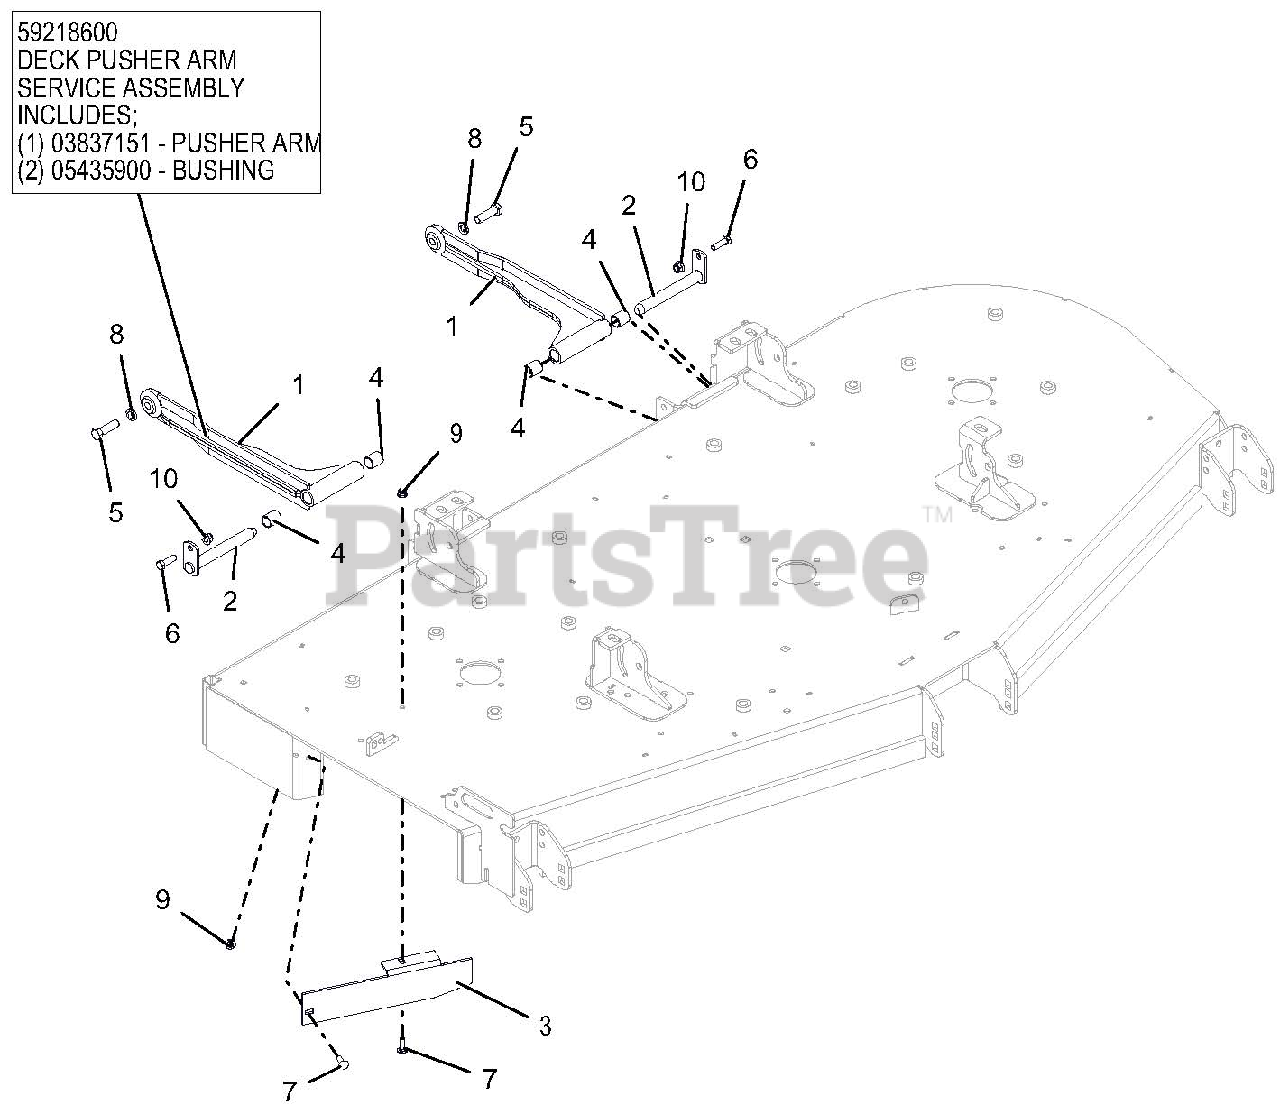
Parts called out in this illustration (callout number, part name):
1	DECK STABILIZER ARM - BLACK
1	DECK STABILIZER ARM W/BUSHINGS
1	BRG, .750 X .875 X 1.000
2	WELDMENT, MOWER MTG. PIN
3	72" DISCHARGE BAFFLE - RED
4	BRG, .750 X .875 X 1.000
5	BLT-HEX .50-13X1.75 GR5EP80 YZ
6	@BLT-HEX .38-16X1.25 GR5 YWZC
7	@BLT-RDHDSQNK .31-18X1.00 G5YZ
8	@WSHR-LK .50X.125 REG YWZC
9	@NUT-LK-NYL-FLG .31-18 YWZC
10	@NUT-LK-NYL-FLG .38-16 YWZC
